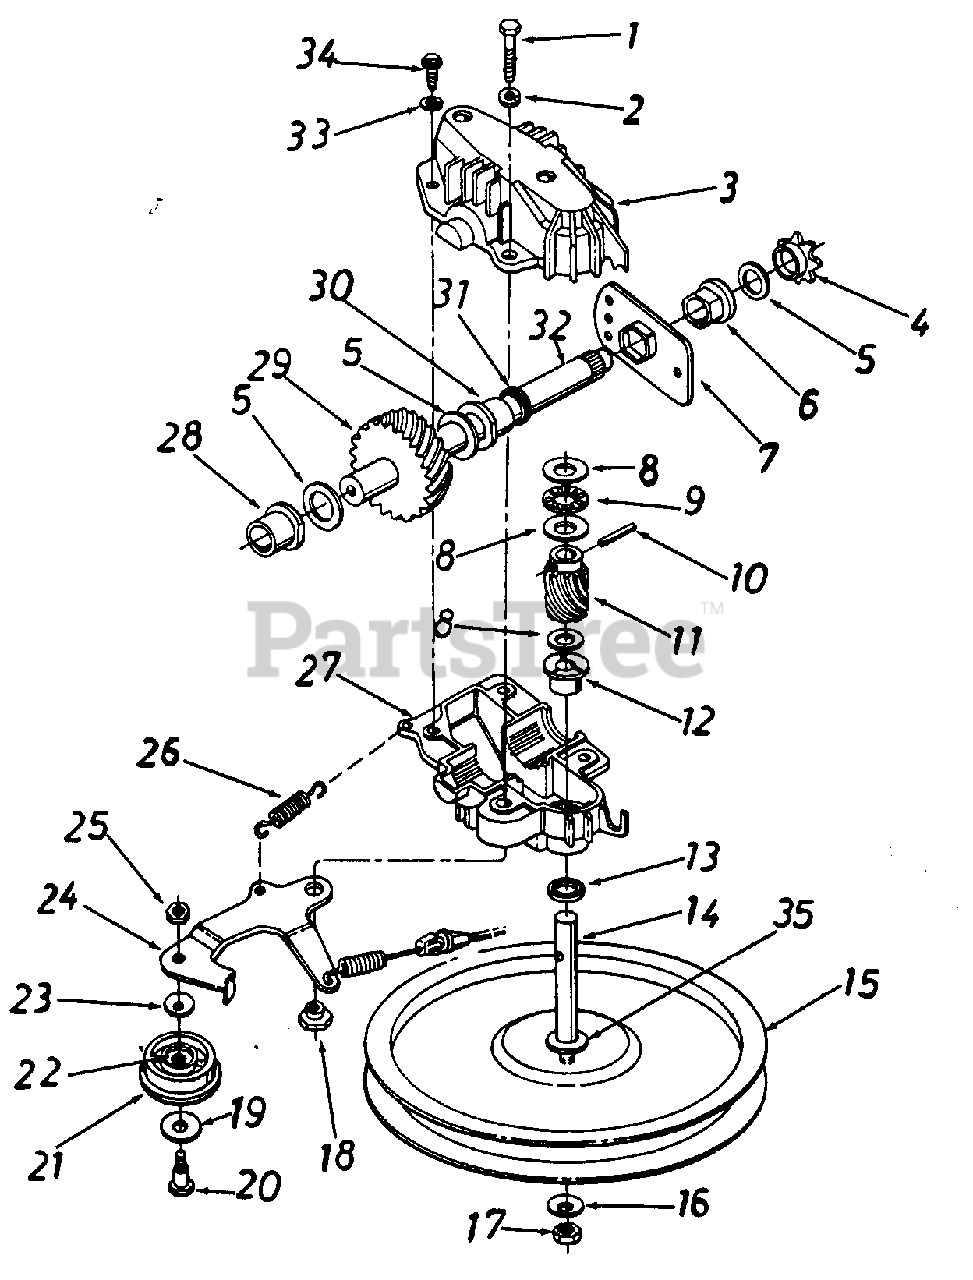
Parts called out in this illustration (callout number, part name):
1	Hex Bolt 1/4-20 x 1.25" Lg.
2	L-Wash. 1/4" I.D.
3	Upper Transmission Hsg. Half
4	#48 Sprocket 7 Tooth x 1/2 Pitch
5	Fl-Wash. 5/8" I.D. x .030
6	Hex Flange Brg. .631" I.D.
7	Hex Bearing Cup
8	Thrust Wash. .382" I.D. x .70" O.D.
9	Thrust Bearing .375" I.D. x .812" O.D.
10	Spring Pin Spir. 1/8" x .62" Heavy
11	11 Tooth Helical Gear
12	Flange Bearing
13	Oil Seal
14	Pulley-Transmission Shaft .375 O.D.
15	Fl-Pulley 5.06" O.D.
16	Bell-Wash. .265" I.D. x .75"t
17	Hex Lock Nut 1/4-28 LH Thd.
18	Shld. Spacer .375" Dia. x . 1 70t
19	Fl-Wash. .390" I.D. x 1.0"t
20	Shld. Bolt .375" Dia. x .40"t
21	Fl-Idler Plastic 1.50" Dia. x .48t
22	Needle Brg. .375" x .31t
23	Bell-Wash. .265" I.D.Ix.75"t
24	Idler Brk't. Ass'y t
25	Hex Patch L-Nut 1/4-28 Thd.
26	Extension Spring 1.12" Lg.
27	Lower Transmission Hsg. Half
28	Flange Bearing .566 Dia.
29	33 Tooth Helical Gear
30	Flange Bearing .629 Dia.
31	Oil Seal .625 Dia.
32	Gear Sprocket Shaft
33	L-Wash. #10
34	Hex B-Tap Scr. #10 x .62"
35	Hex Washer .26" x .88"t
